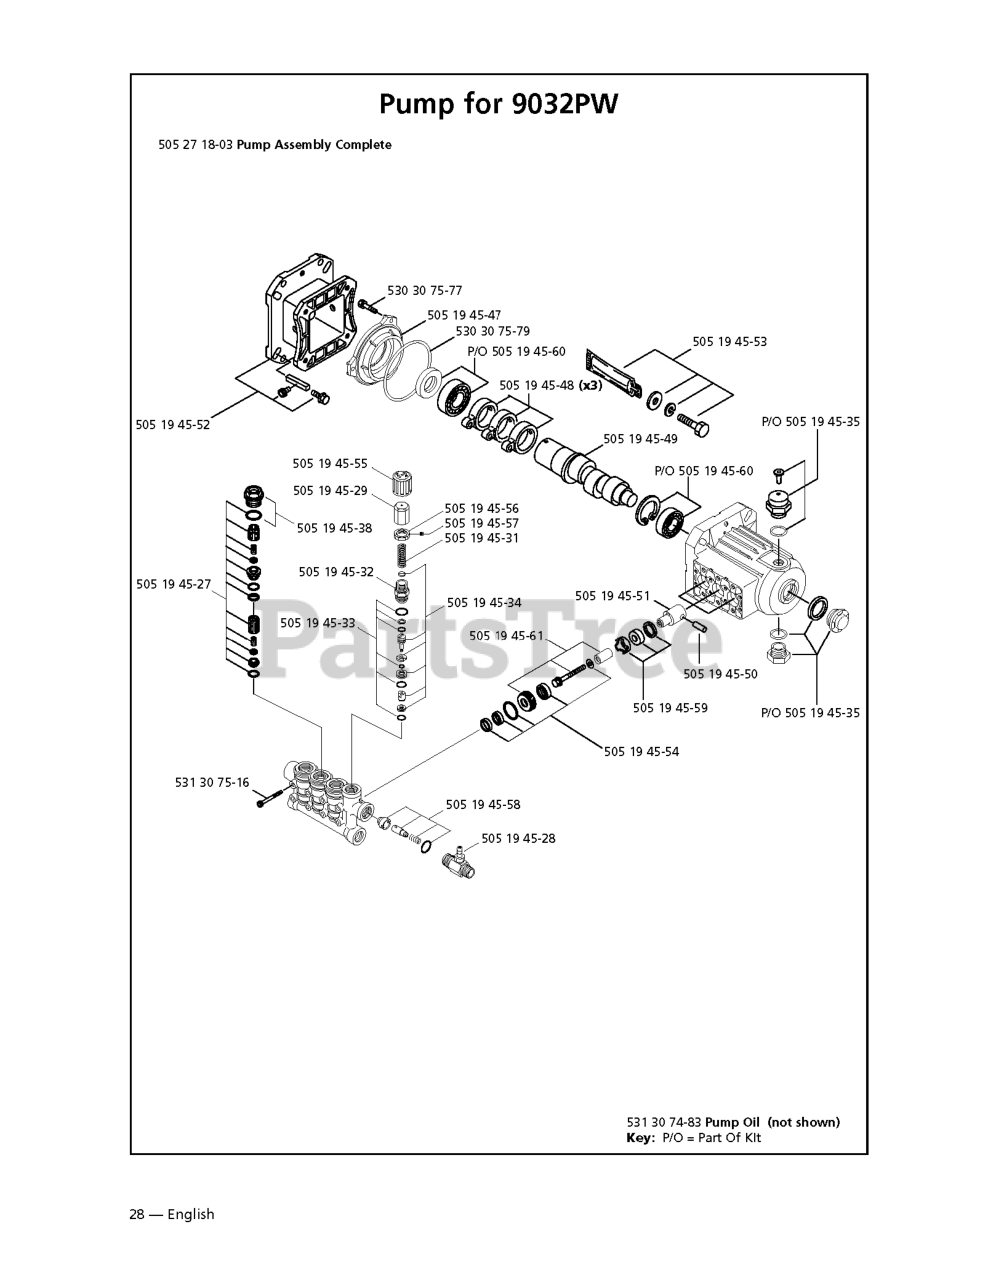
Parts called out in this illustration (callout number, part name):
1	SEAT.XG090.BLK.KB/BLT.NO-LOG
2	SEAT PIVOT BRKT
3	BOLT, HEX 3/8-16X1
6	NUT
7	SPRING COMPRESSION
8	SCREW 3/8-16X1
9	WASHER
10	PAN.ASM.SEAT.1SLOT
12	BRKT.MNTNG.SWITCH.SEAT.BLACK
14	BOLT.ROUND.HEAD.SQUARE.NECK
15	SPACER SPLIT 28X.96
17	NUT T
21	BOLT.SHOULDER.5/16-18
22	NUT.71038.31-18.HEX.NYLOCK
23	BOLT.HEX.BLACK
25	BOLT,SHOULD
26	LOCKWASHER
